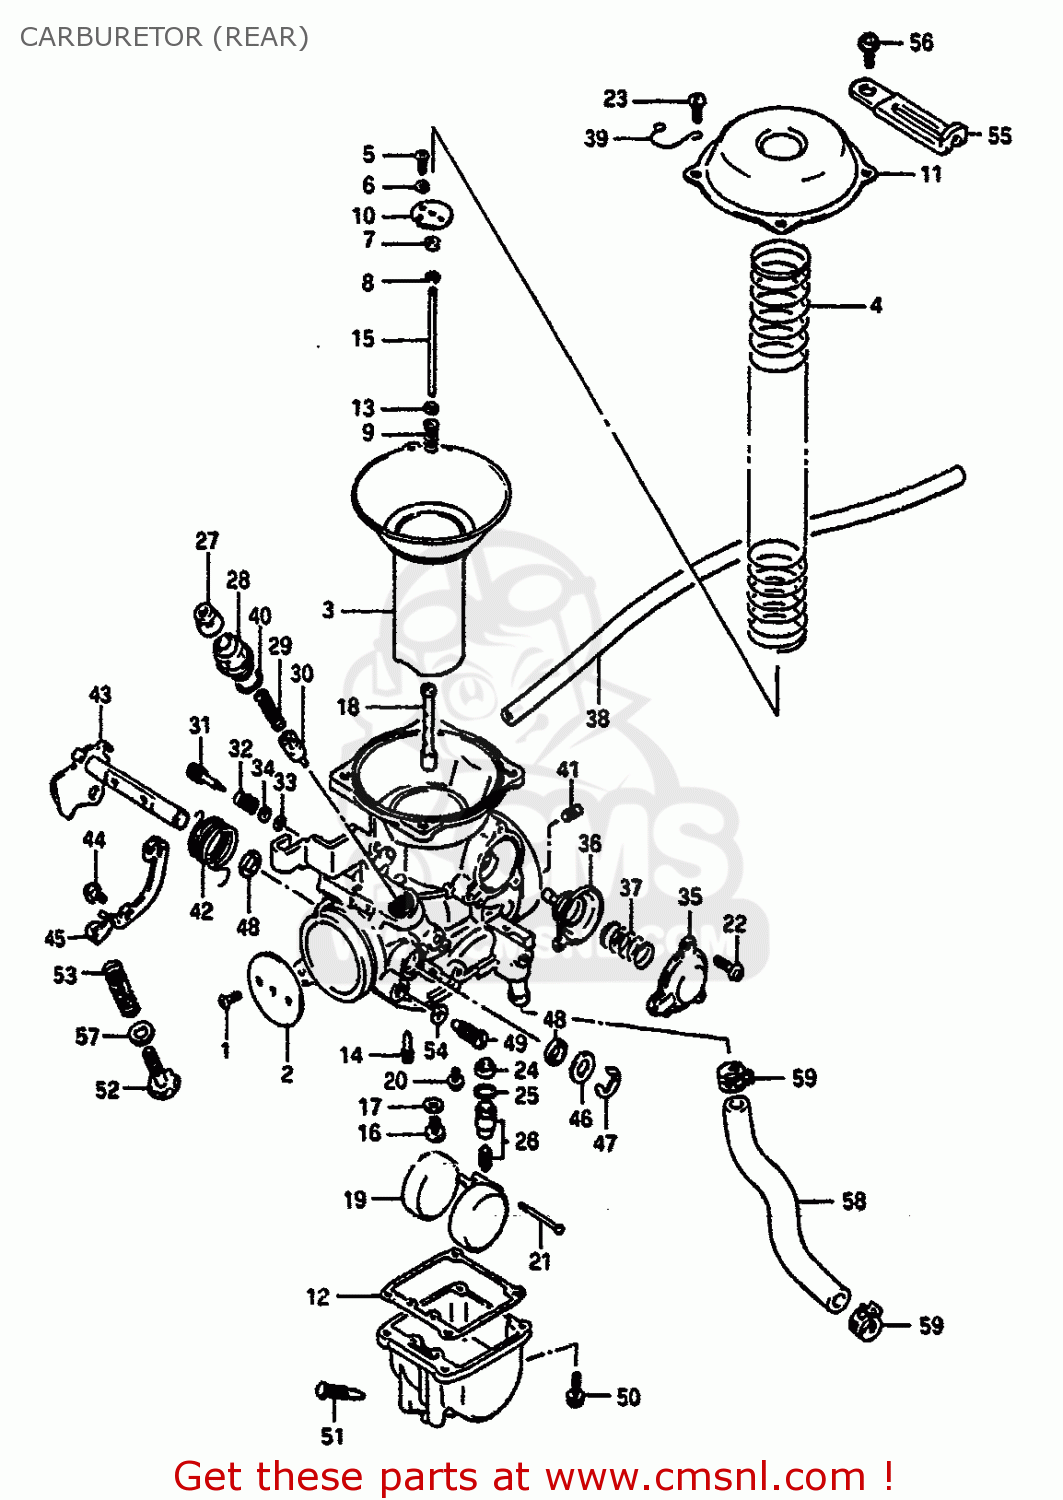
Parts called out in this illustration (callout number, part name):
1	SCREW
2	VALVE,THROTTLE
3	DIAPHRAGM,CARBURETOR
4	SPRING,DIAPHRAGM
5	SCREW
6	LOCK WASHER
7	RING
8	CLIP
9	SPRING
10	PLATE
11	COVER,DIAPHRAGM
12	GASKET,FLOAT CHAMBER (NAS)
13	WASHER
14	JET(40)
15	NEEDLE,JET
16	JET,MAIN(110)
17	WASHER,NEEDLE NOZZLE
18	JET,NEEDLE
19	FLOAT
20	SCREW
21	PIN,FLOAT
22	SCREWM4X0.7X10
23	SCREW
24	FILTER
25	O-RING,NEEDLE VALVE
26	VALVE ASSY,NEEDLE
27	CAP
28	HOLDER,GUIDE
29	SPRING
30	PLUNGER
31	SCREW,PILOT AIR
32	SPRING
33	O RING,PILOT AIR SCREW
34	WASHER
35	COVER
36	DIAPHRAGM ASSY
37	SPRING
38	HOSE
39	CLIP
40	O RING
41	JET
42	SPRING
43	SHAFT ASSEMBLY
44	SCREW
45	LEVER,ASSY
46	GASKET,THROTTLE SHAFT (NAS)
47	E RING
48	SEAL,THROTTLE SHAFT
49	SCREW
50	SCREW
51	PLUG,DRAIN
52	ADJUSTER
53	SPRING
54	WASHER
55	CLIP
56	SCREW
57	WASHER
58	HOSE
59	CLIP
